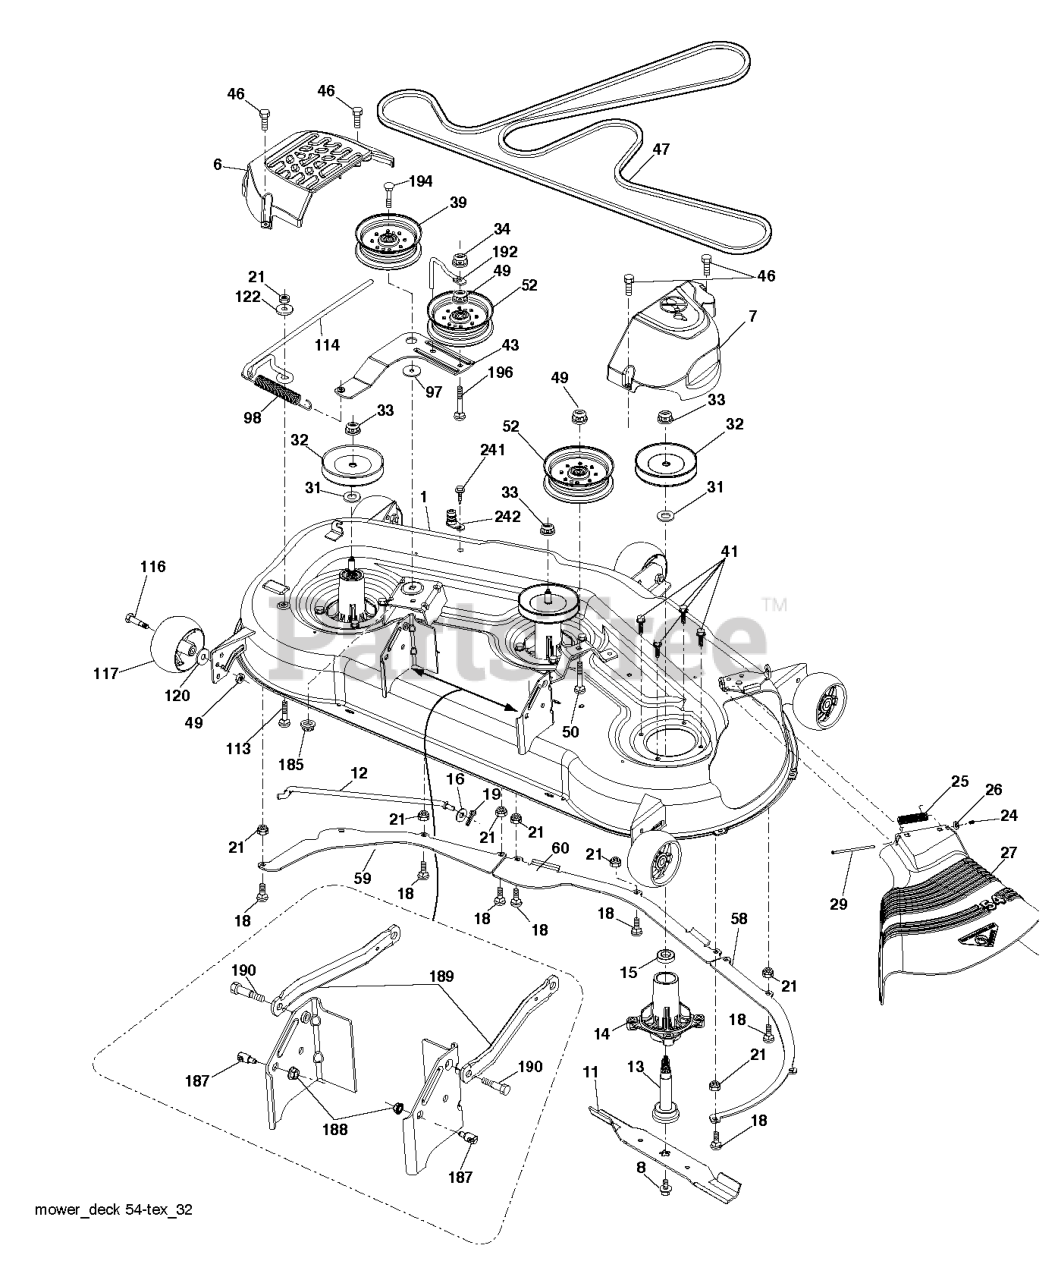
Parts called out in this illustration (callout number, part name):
1	DECK.WELDMENT.54"MS-498
6	COVER.MANDREL.LH.54"20
7	COVER.MANDREL.RH.54.20
8	BOLT.WASHER.ASM.7/16-2
11	BLADE.BAGGING.54"
11	54" MULCH BLADE
12	ROD.ANTI.SWAY.48/54"K4
13	SHAFT ASM MANDREL
14	RP.HOUSING.MANDREL.4PT.
16	WASHER
18	BOLT
19	PIN.COTTER.5/16.BOW TI
21	LOCKNUT
24	CAP-SLEEVE LT
25	SPRING, TORSION
26	NUT PUSH M
27	DEFLECTOR
29	ROD.HINGE
30	SCREW, WASHER HEAD
31	WASHER.SPACER.MANDREL
32	PULLEY/MANDREL
33	NUT.FLANGE.LOCK.TOP
39	RB PULLEY.IDLER.4.50/HUB SPEC
43	ARM.IDLER
46	SCREW.1/4-20X5/8
47	RP.BELT.DRIVE.54."2006
49	NUT LOCK FLG 3/8-16 UNC
50	BOLT
52	PULLEY.IDLER.2006
58	BAFFLE.RIGHT.54"
59	BAFFLE.LEFT.54"
60	BAFFLE CENTER 54" MOWER
98	SPRING, DECK DRIVE
113	BOLT CRT
114	ROD TENSION RELIEF
116	BOLT.SHOULDER.3/8-16X3-5/8.
117	RP WHEEL. GUAGE RALLY
120	WASHER
122	BUSHING.RELIEF.TENSION
185	NUT.LOCK.FLANGE.7/16
187	STUD.FASTNER.W/ANTI-ROTATE
188	NUT LOCK HEX FLANGE 5/16-18
189	ARM.SUSPENSION.MOWER
190	BOLT.SHOULDER
192	KEEPER.BELT.IDLER.54"T
194	BOLT.HEX.WASHER.HEAD.7/16-24X
196	BOLT
241	SCREW.TT.#10-32X.5.3/8.FLANGE
242	PORT.WASHOUT
